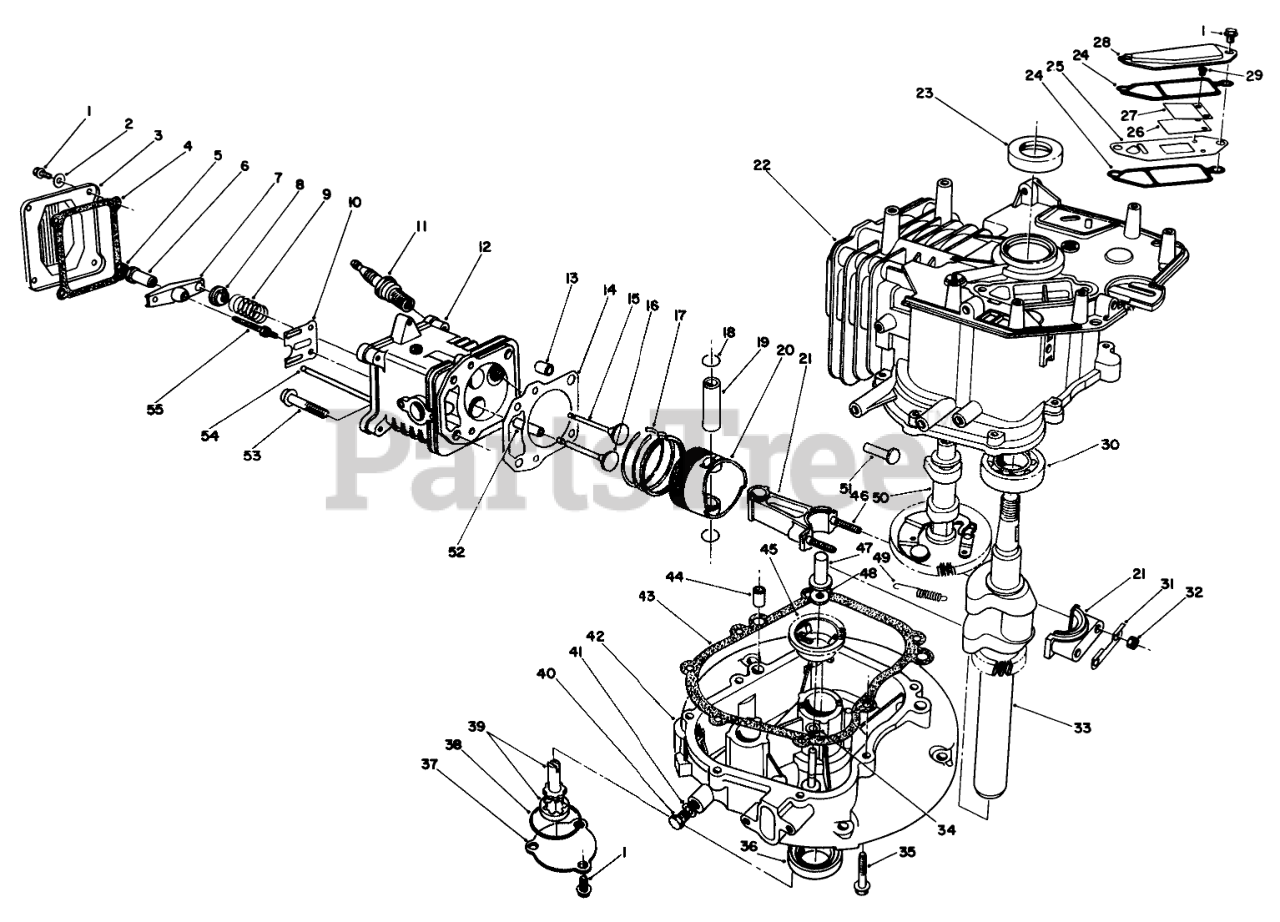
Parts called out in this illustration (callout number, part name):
2	WASHER
3	COVER
4	GASKET
6	PIVOT
8	RETAINER
9	SPRING
10	GUIDE
11	SPARK PLUG
12	Head-Cylinder (Incl. Ref. #52)
14	GASKET
15	VALVE-INTAKE
16	VALVE-EXHAUST
17	RING SET
18	CIRCLIP
20	PISTON
21	Connection Rod Assembly (Incl. Ref. #31, 32, & 46)
22	Block-Engine (Incl. Ref. #23, & 30)
24	GASKET
25	Plate-Breather
26	Valve-Reed
27	Retainer-Reed Valve
28	COVER
29	Screw-Reed Valve
30	BEARING
31	Plate-Lock
33	CRANKSHAFT
34	WASHER
37	COVER
38	O-RING
39	OIL PUMP
40	OIL DRAIN PLUG
41	GASKET
42	Crankcase
43	GASKET
45	GOVERNOR FLYWEIGHT ASM
47	PLUNGER
48	WASHER
49	SPRING
50	Camshaft Assembly (Incl. Ref. #49)
51	TAPPET
52	GUIDE
